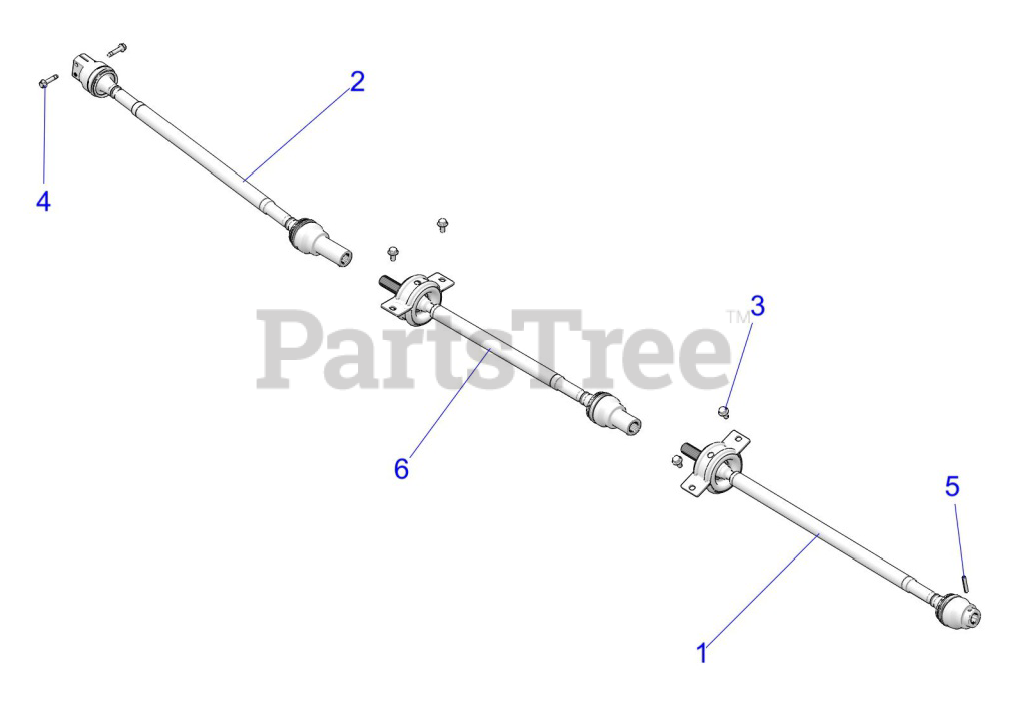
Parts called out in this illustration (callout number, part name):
1	ASM-PROPSHAFT- FRONT
2	ASM-PROPSHAFT- REAR
3	BOLT-M10X1.5X20-HXFLG-W/PATCH
4	SCR-HXFL-M8X1.25X40 8.8 ZODP30
5	PIN-SPRING(10)
6	ASM-PROPSHAFT,MID
